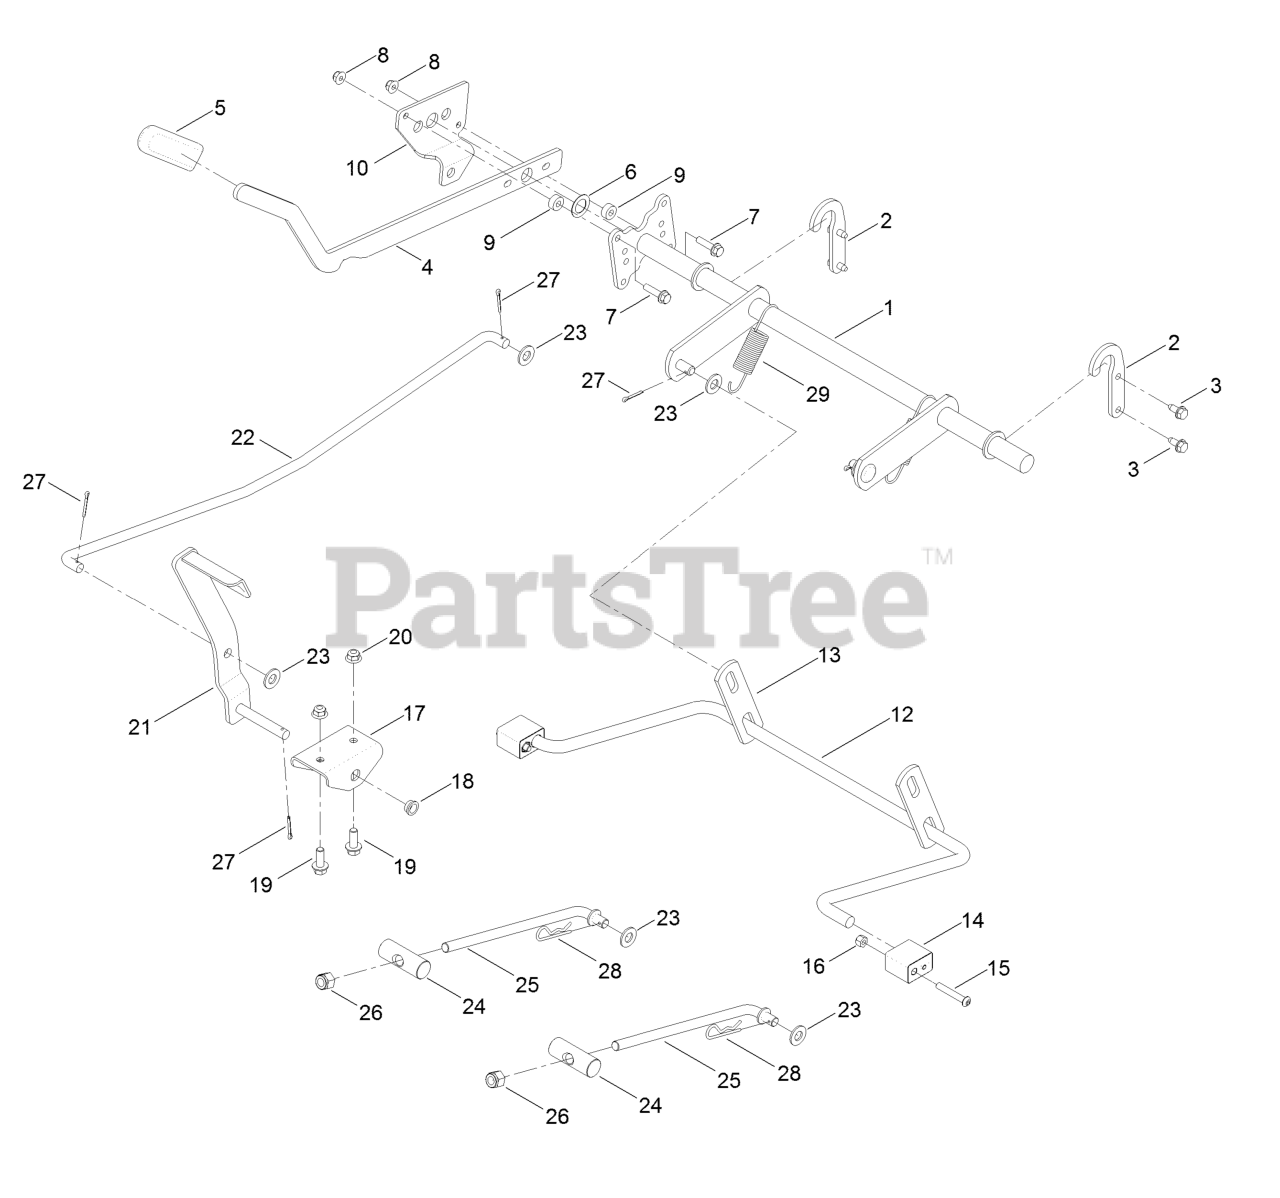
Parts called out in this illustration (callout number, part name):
1	DECK LIFT ASM
2	BRACKET-LIFT
3	Screw-HWH 5/16-18 X 3/4 Tf
4	LEVER-LIFT
5	GRIP-LEVER
6	WASHER-THRUST
7	SCREW-HHF
8	NUT-HF, NI
10	PLATE-FOOTLIFT
12	ARM-LIFT, REAR (WIDE)
13	LINK-LIFT
14	BLOCK-PIVOT
15	SCREW-HSBH
16	NUT-LOCK, NI
17	BRACKET-FOOTLIFT
18	BUSHING-FLANGE
19	SCREW-HHF 3/8-16 X 1
20	NUT-HF, NI
21	PEDAL ASM
22	ROD-FOOTLIFT
23	WASHER-FLAT
24	PIN-PIVOT
25	ROD-MOUNT, DECK
26	NUT-HEX
27	PIN-COTTER
28	PIN-COTTER
29	SPRING, EXTENSION
